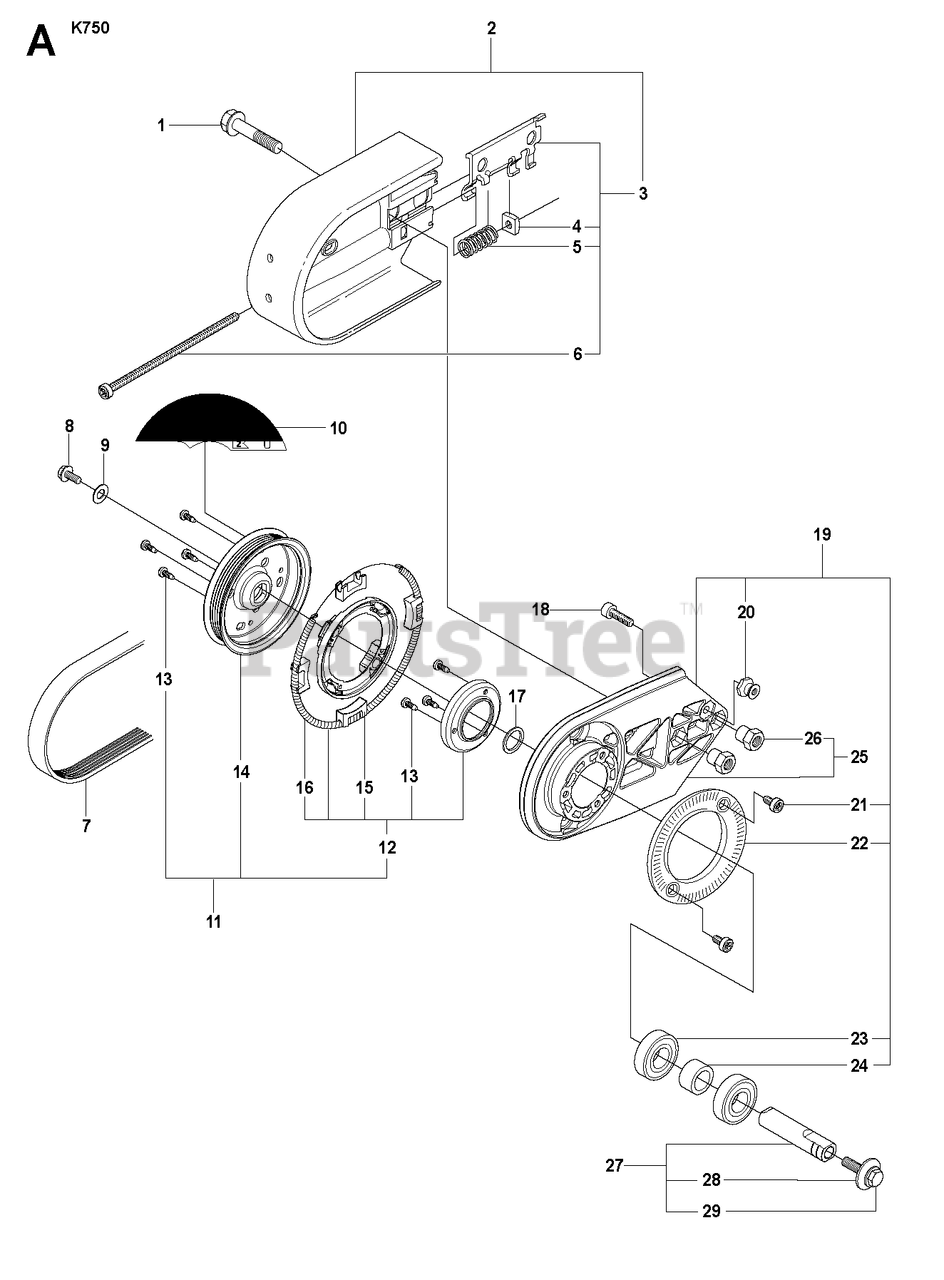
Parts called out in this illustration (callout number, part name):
1	SCREW EHHFM
2	BELT GUARDIncl. 3
3	BELT TENSIONER ASSYIncl. 4 - 6
5	COMPRESSION SPRING
6	SCREW CITXSCM
11	PULLEYIncl. 12 - 16
12	PULLEYIncl. 13, 15, 16
13	SCREW CCRPANT
14	PULLEY
19	BEARING HOUSINGIncl. 20 - 24
20	TORSION STOP
21	SCREW ITXSCM
23	BALL BEARING
25	BEARING HOUSINGIncl. 26
27	SHAFTIncl. 28, 29
